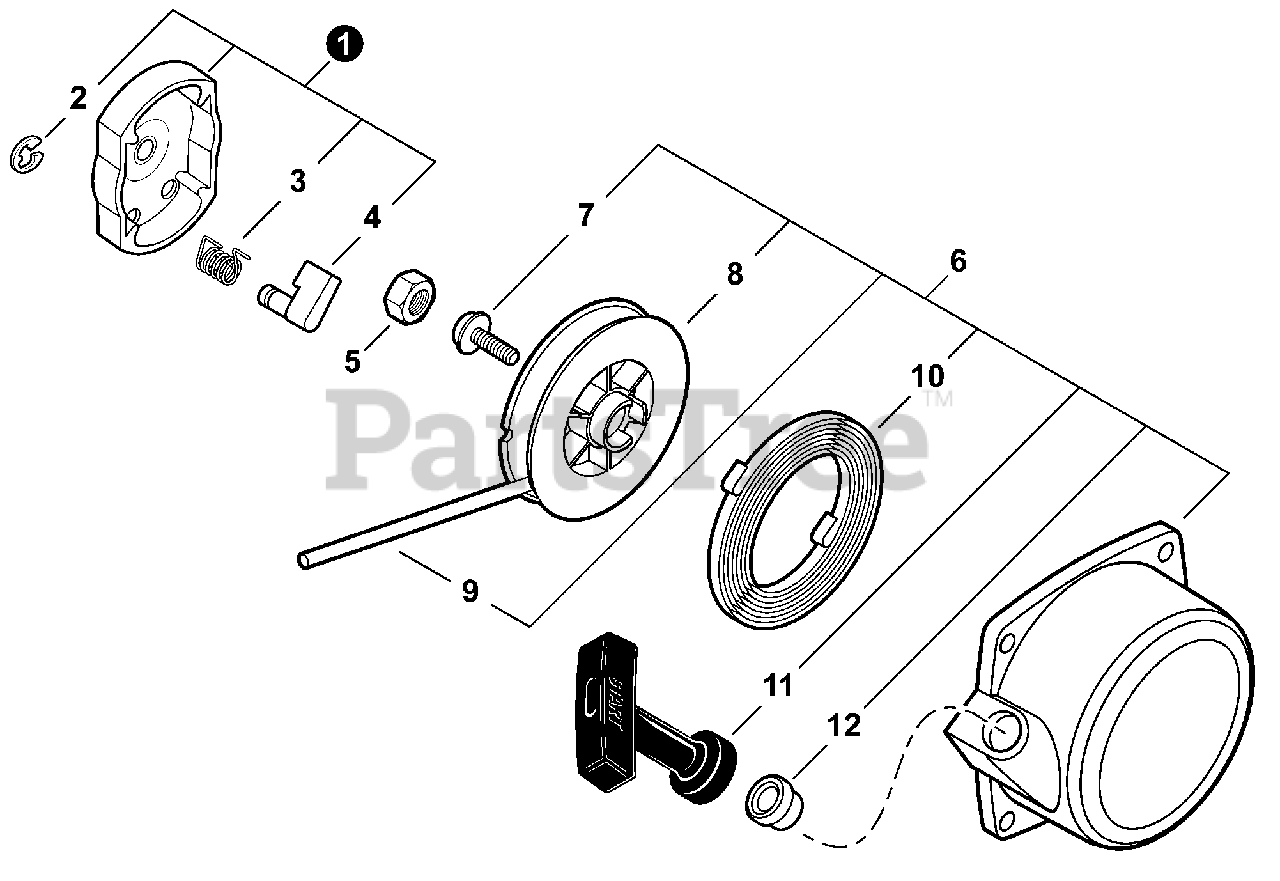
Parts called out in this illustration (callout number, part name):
1	PULLEY ASSY, STARTER
2	E-RING 4
3	SPRING, RETURN
4	PAWL
5	NUT 8×1.25
6	STARTER ASSY, RECOIL
8	REEL, ROPE
9	ROPE, STARTER 3.8×1150
10	SPRING, RECOIL
11	GRIP, STARTER
12	GUIDE, ROPE
